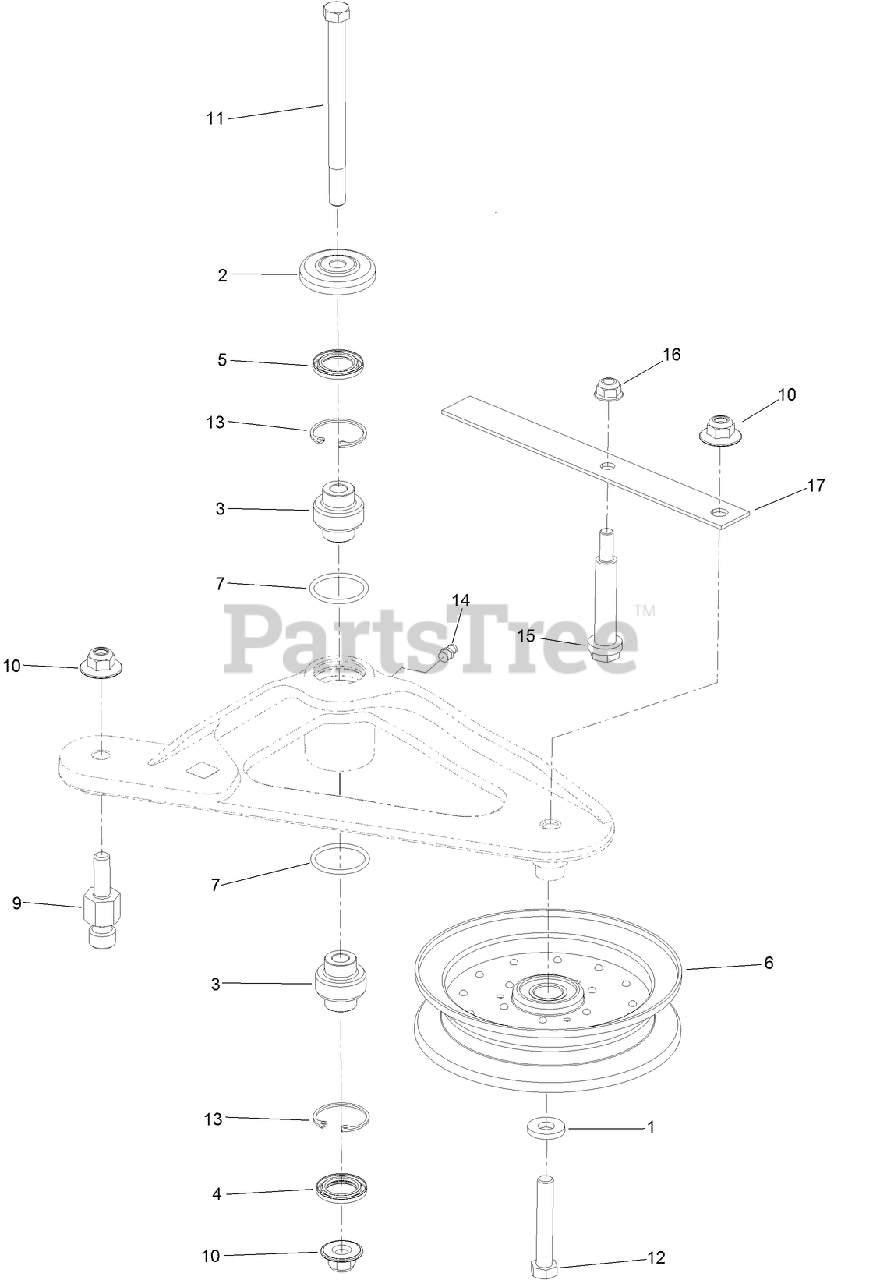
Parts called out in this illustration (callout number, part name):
1	SPACER
2	GUARD-TOP
3	BEARING-SPHERICAL
4	Seal-Lip, Double
5	SEAL-LIP, SINGLE
6	IDLER-PULLEY, FLANGED
7	O-RING
9	PIN-SPRING, ANCHOR
10	NUT-FLANGE, NI
11	SCREW-SHOULDER, HH
12	SCREW-HH
13	RING-SNAP
14	FITTING-GREASE
15	BOLT-SHOULDER
16	NUT-HF, NI
17	SPRING-BELT
